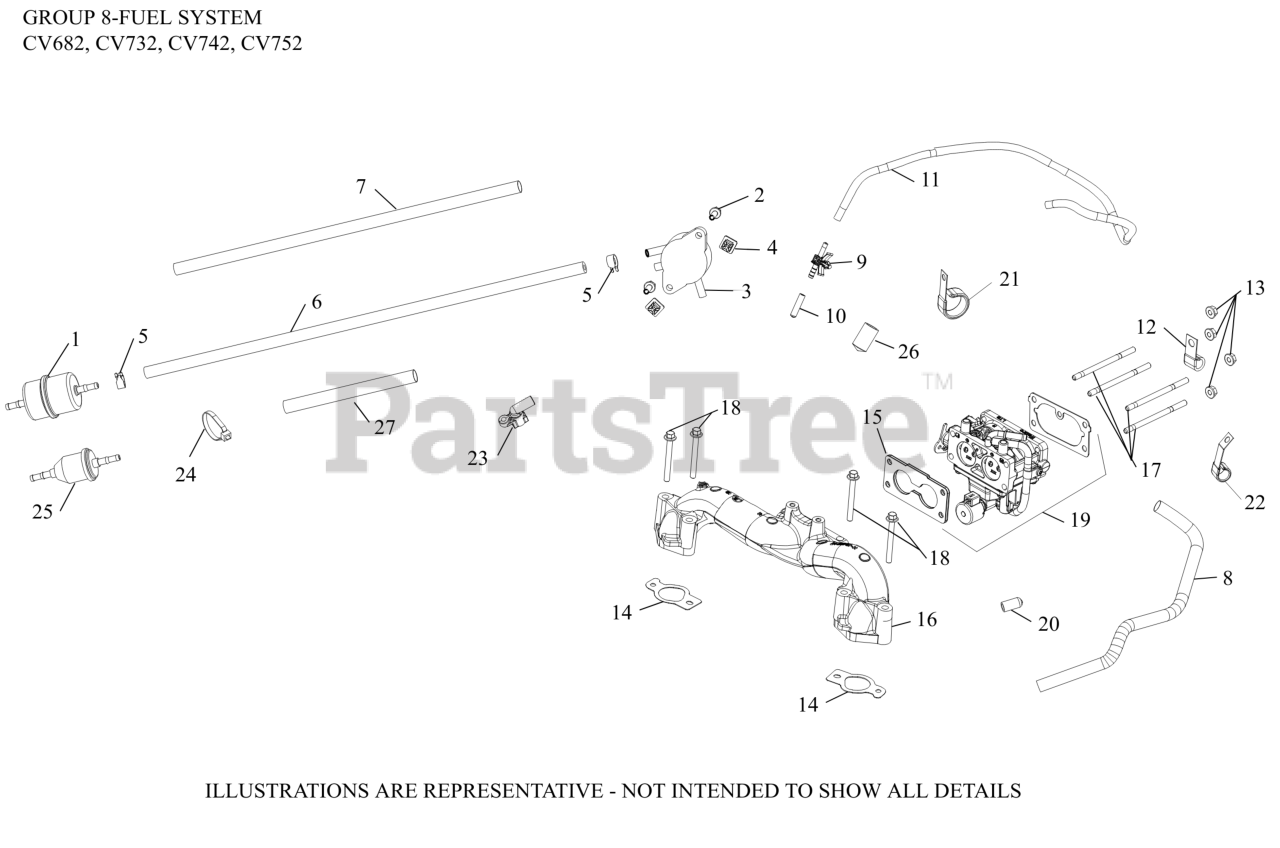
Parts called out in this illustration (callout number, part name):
2	SCREW, TAP M6X1.7X18
3	PUMP, FUEL
4	NUT, PLASTIC - BLACK
5	CLAMP, HOSE (KM)-USE 25 237 31-S
5	SPRING CLAMP, HOSE
6	HOSE,LW PERM.FUEL 24.00"-USE 25 111 81-S
8	SLEEVE, INSULATING 14"
8	SLEEVE, ANTI-ABRASION
9	CONNECTOR, EVAPORATIVE
10	CAP, MASKING
11	HOSE, EVAPORATIVE
13	NUT, FLG M6X1.0
14	KIT, INTAKE MANIFOLD GASKET
15	GASKET, CARBURETOR-USE 24 041 84-S
15	GASKET, CARBURETOR
16	KIT, MANIFOLD INTAKE (VERTICAL 2BBL)
17	STUD,M6X1.0X96
18	SCREW, FLG M6X1.0X55
19	KIT, CARBURETOR-USE 24 853 270-S
25	FILTER,FUEL 51 MICRON (FUEL PUMP)
